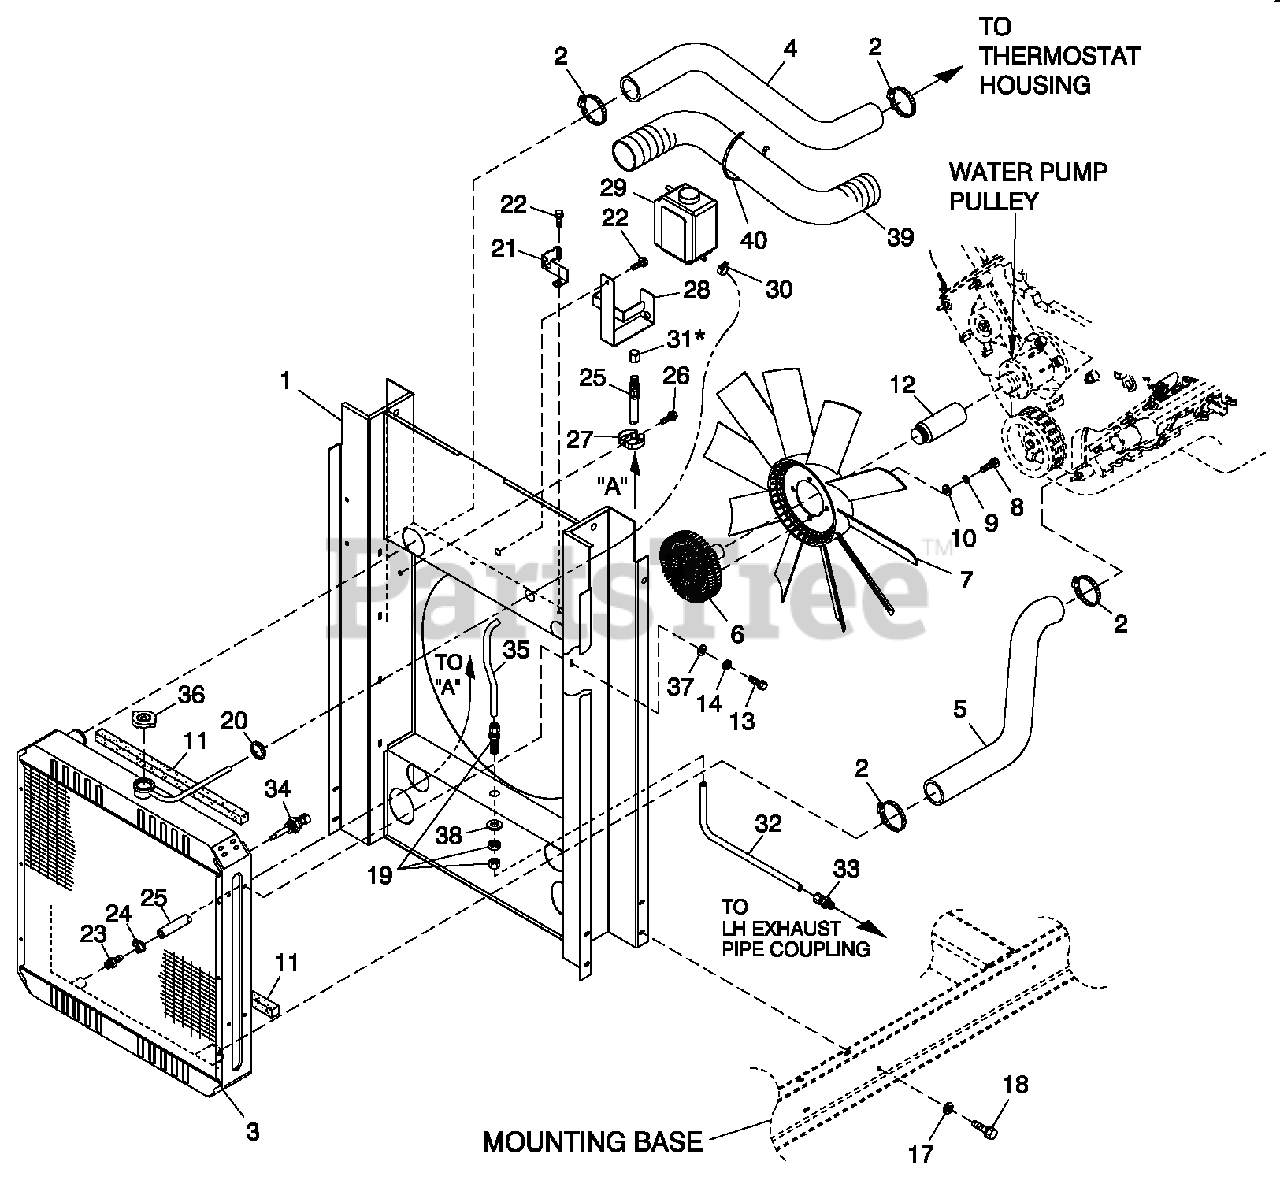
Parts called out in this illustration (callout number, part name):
1	WELDMENT RAD SUPPORT C3 (22")
2	CLAMP HOSE #281.32-2.25
3	RADIATOR 581 X 585 X 70 CPL LH
4	HOSE UPPER RADIATOR C3
5	HOSE LOWER RADIATOR C3
6	CLUTCH COOLING FAN
7	FAN 22" D IA 10 BLADE
8	SCREW HHC M10-1.5X 20 G8.8
9	WASHER LOCK M10
10	WASHER FLAT 3/8-M10 ZINC
11	TAPE FOAM 1 X 1 (23" LG)
12	SPACER FAN 6.8L
13	SCREW HHC M8-1.25X 20 G8.8
14	WASHER LOCK M8-5/16
17	WASHER LOCK M6-1/4
18	SCREW HHFC M6-1.0X 20 G8.8
19	FTG CMPN BLKHD 3/8" OD TUBE BRS
20	RO M M E T .7 5X .12X .5 0
21	BRACKET SIGNAL CONDITIONER
22	SCREW THF M6-1 X 16 N WA Z/JS
23	BARBED STR 3/8 NPT X 3/8
24	CLAMP HOSE .38-.87
25	HOSE DRAIN ASSY 28"
26	SCREW HHTT M 4-0 .7X 8B P
27	SPRING CLIP HOLDER .37-.62
28	BRKT COOLANT RECOVERY TANK
29	TANK COOLANT RECOVERY
30	CLAMP HOSE BAND 1/4
31	CAP HEX 1/4 NPT BRASS
32	TUBE FAN CLUTCH PREHTR LOWR C3
33	FTG CMPR 3/8TUBE X 3/8 NPT W/FERL
34	PROBE COOLANT LEVEL 3/8 NPTF (USE WITH HARN P/N 0F5990 & 0F5991)
35	TUBE FAN CLUTCH PREHTR UPPR C2
36	CAP RADIATOR 13 PSI
37	WASHER FLAT 5/16-M8 ZINC
38	WASHER FLAT 9/16 ZINC
39	CONDUIT FLEX 2.0"ID
40	TIE WRAP UL 14.6 X .1 4 BLK
